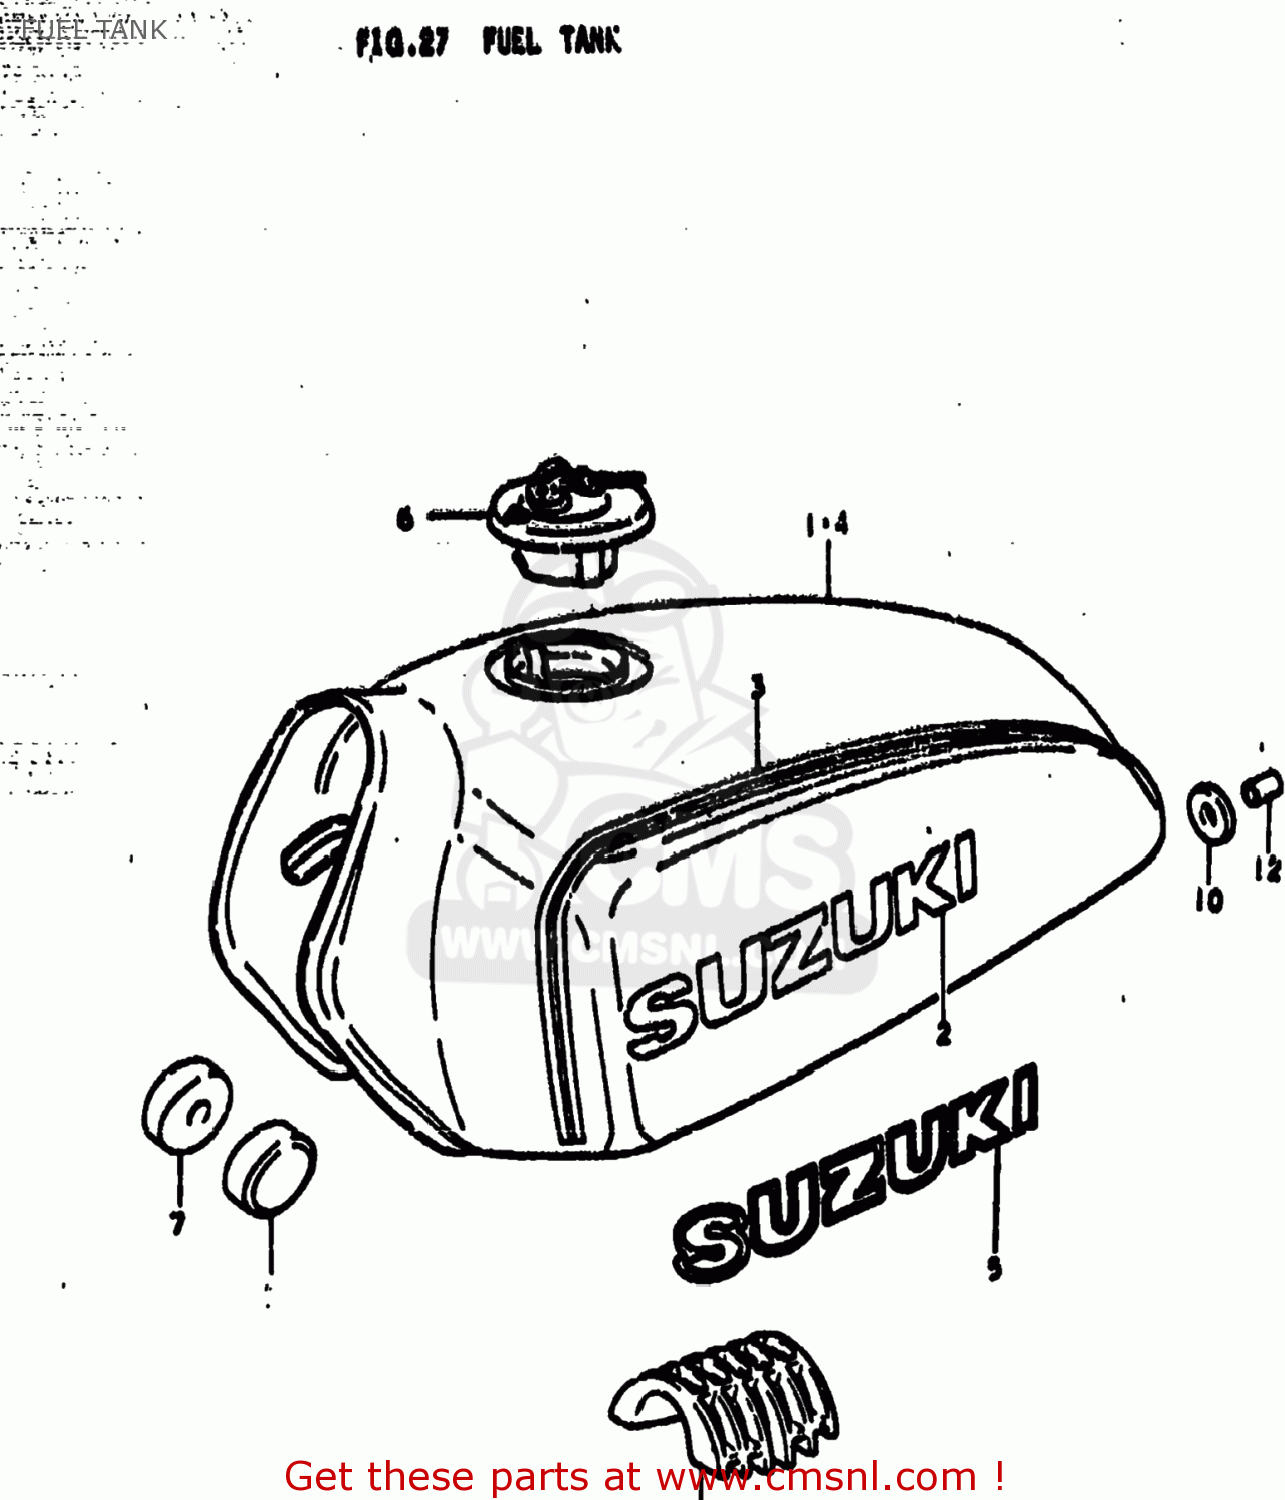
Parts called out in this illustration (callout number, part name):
1	TANK ASSEMBLY,FUEL
2	EMBLEM
3	TAPE SET
4	TANK ASSEMBLY,FUEL
5	EMBLEM
6	CAP SET,FUEL TANK
7	CUSHION
8	CUSHION
9	CUSHION
10	CUSHION
11	WASHER (8.5X29X1.6)
12	SPACER (8.2X12X17)
13	BOLT (8X30)
